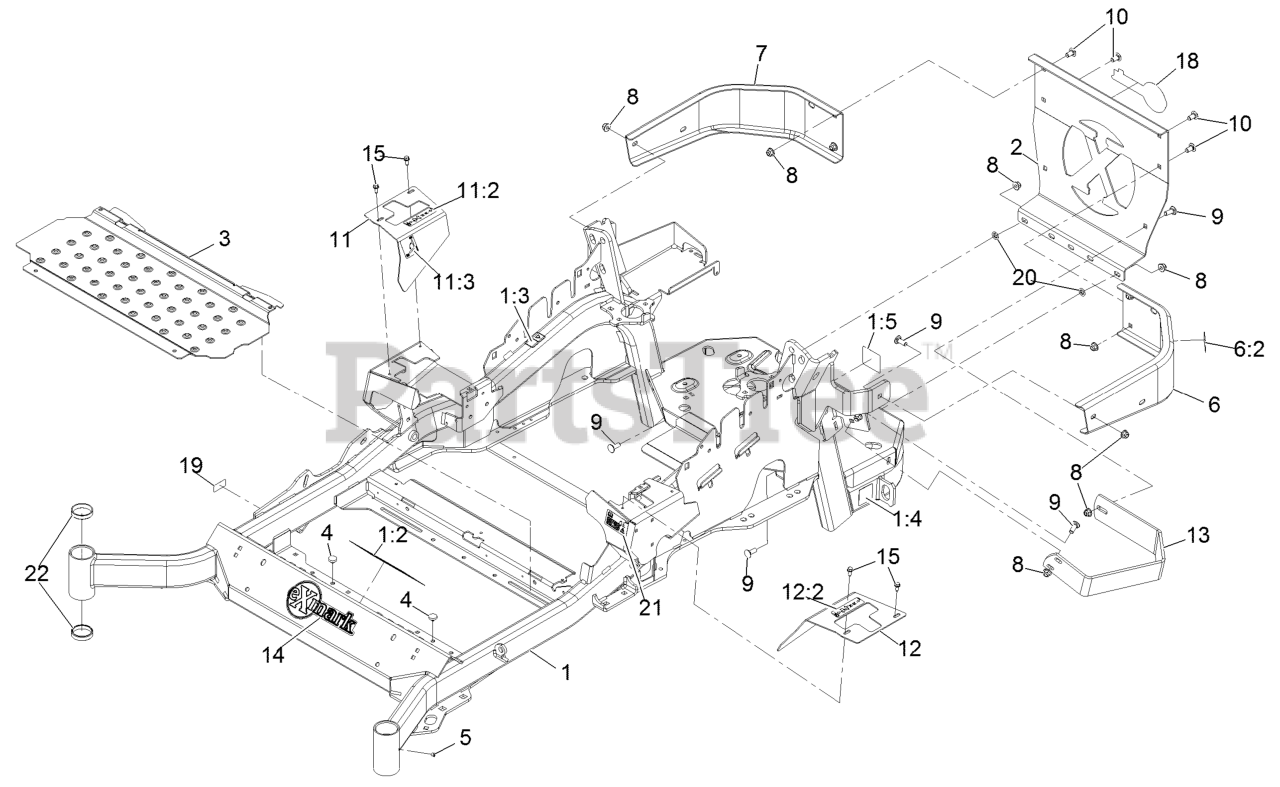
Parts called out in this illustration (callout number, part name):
1	MAINFRAME ASM
1:2	DECAL-DANGER
1:3	DECAL-WARNING
1:4	DECAL-HAZARD, PINCHED FINGER
1:5	DECAL-SPARK ARRESTER
2	PLATE,REAR GUARD
6	LH BUMPER ASM
6:2	DECAL-WARNING
7	BUMPER-RH
8	NUT-HF, NI
9	SCREW-CARR
10	SCREW-CARR
11	RH MOTION CONTROL COVER ASM
11:2	DECAL-CONTROL, MOTION
11:3	DECAL-PARK BRAKE, CE
12	LH MOTION CONTROL COVER ASM
12:2	DECAL-CONTROL, MOTION
13	GUARD-MUFFLER
14	DECAL-EXMARK LOGO
15	SCREW-HWH
18	DECAL-EXMARK LOGO
19	Decal-Patent
20	NUT-PUSH
21	DECAL-FUEL FILL, CE
22	CUP-BEARING
